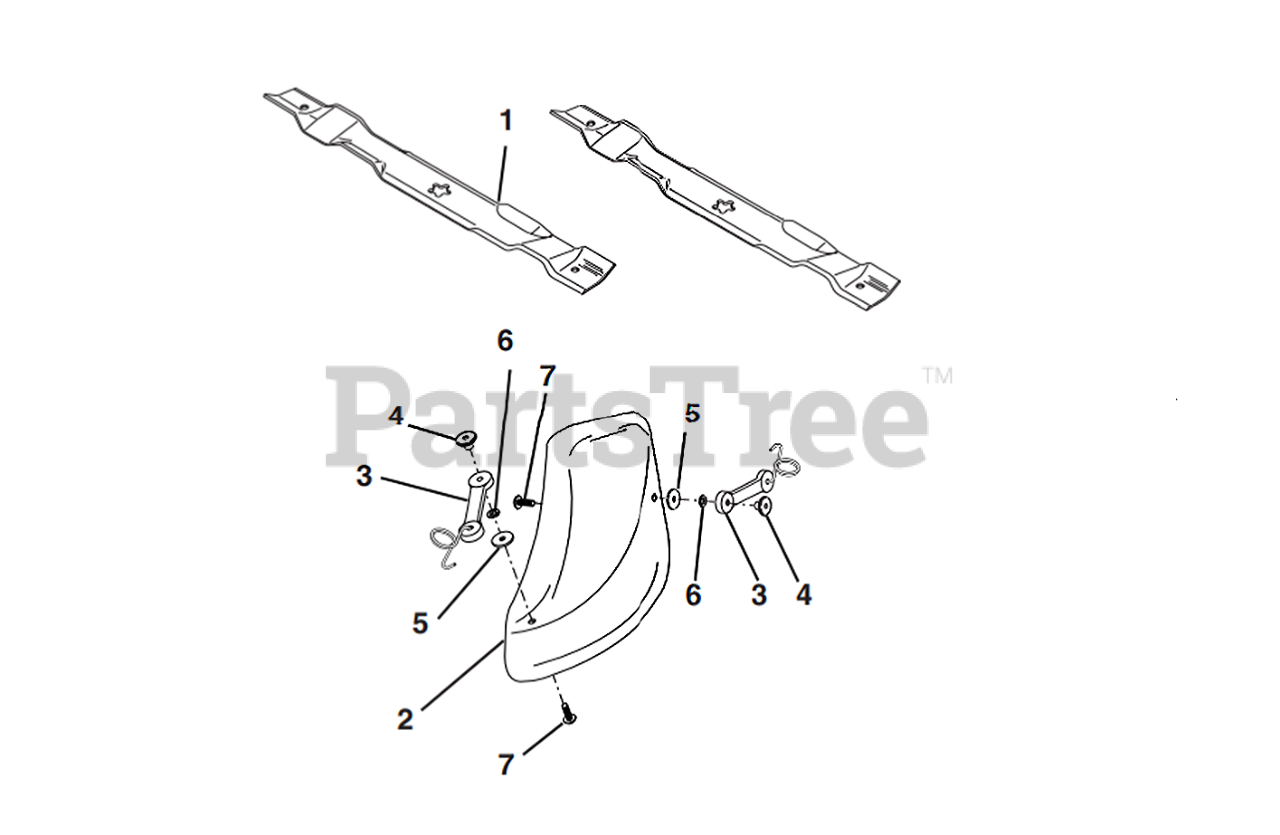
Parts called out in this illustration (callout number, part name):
1	BLADE.42".MULCH
2	COVER.MULCHING.42"
3	LATCH.ASM.MULCH/BAGGER
6	LOCKWASHER #10
